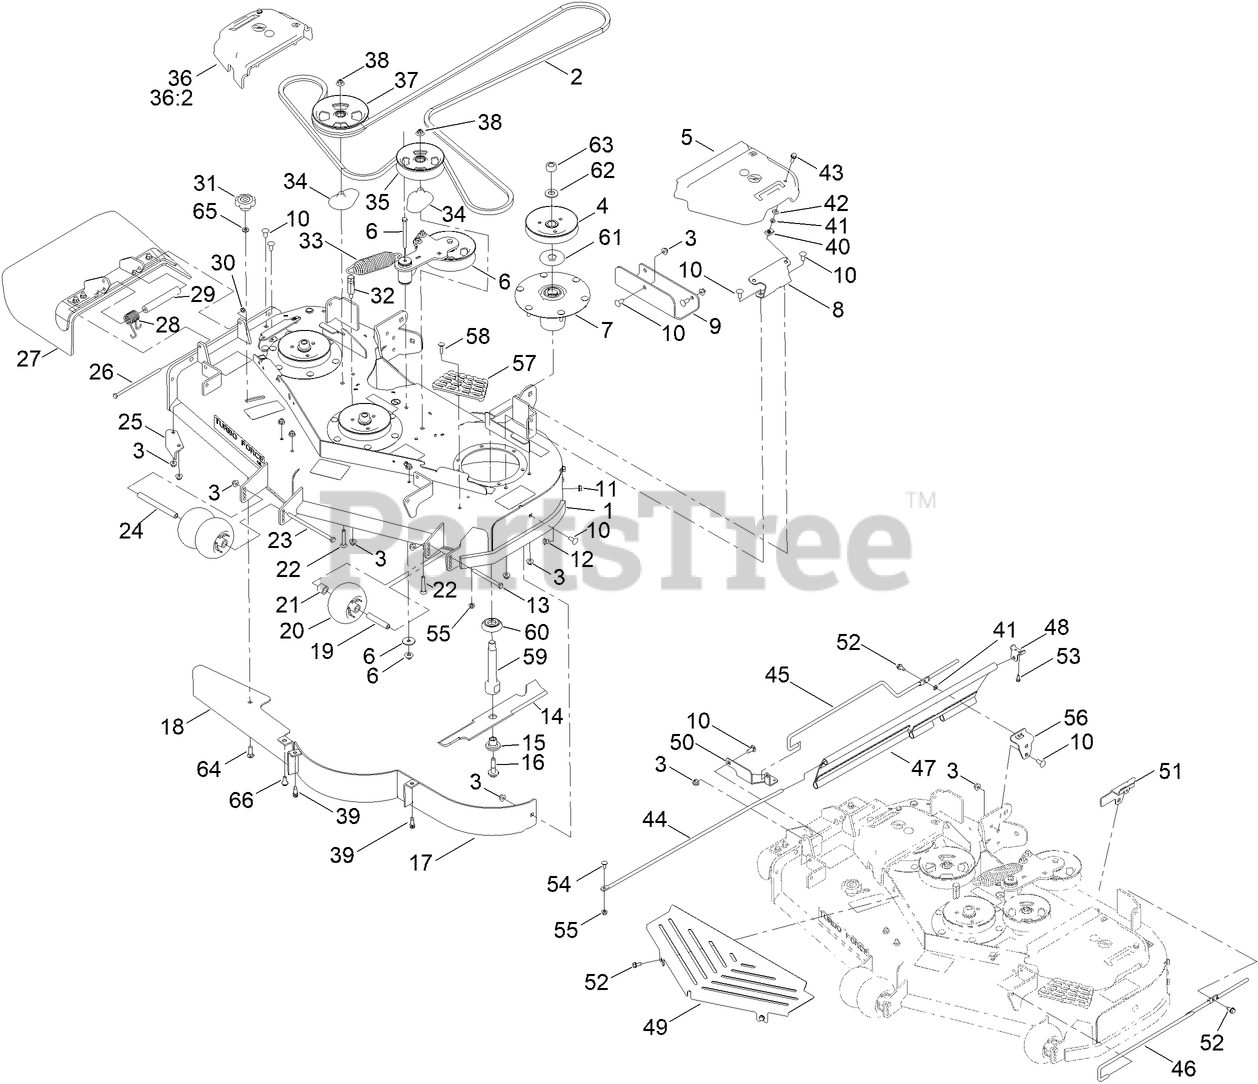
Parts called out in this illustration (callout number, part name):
1	DECK DECAL ASM
2	BELT-V
2	PLUG-PLASTIC
3	NUT-HF, NI
4	SHEAVE,BLADE DRIVE 5.91
5	LH BELT COVER ASM
6	IDLER ARM ASM
7	SPINDLE ASM
8	BRACKET-COVER, BELT
9	PLATE-SKID
10	SCREW-CARR
11	NUT-HHF, WHIZ
12	SCREW-CARR
13	SCREW-HH
14	BLADE-16.50 HIGH FLOW
15	BUSHING-HEX
16	SCREW-SEMS
18	PLATE-BAFFLE, FORMED
19	TUBE-SPANNER
20	ROLLER-SCALP, ANTI
21	TUBE-SPACER
22	BOLT-CARR, SHORT NECK
23	SCREW-HH
24	SPACER-WHEEL
25	BAFFLE-DISCHARGE
26	SCREW-HH
27	RUBBER DEFLECTOR ASM
28	SPRING-TORSION
29	SPACER
30	NUT-LOCK, NI
32	ANCHOR-SPRING, TALL
33	SPRING-EXTENSION
34	SPACER-PULLEY
35	PULLEY-IDLER,FLAT
36	RH BELT COVER ASM
36:2	PLUG-PLASTIC
37	PULLEY-IDLER, FLAT
38	NUT-FLANGE, NI
40	NUT-U
41	NUT-PUSH
42	WASHER-THRUST
43	SCREW-HHF
44	ROD-SUPPORT, UPPER
45	ROD-SUPPORT, LOWER (RH)
46	ROD-SUPPORT, LOWER (LH)
47	GUARD-SIDE
48	BRACKET-MOUNTING, UPPER
49	SHIELD-FRONT
50	BRACKET-MOUNTING, FRONT
51	BRACKET-MOUNTING, REAR (LH)
52	SCREW-HWHTF
53	SCREW-HWH
54	SCREW-CARR
55	NUT-HF, NI
56	BRACKET-MOUNTING, REAR (RH)
57	STEP-DECK
58	SCREW-CARR
59	SHAFT-SPINDLE
60	GUARD-BOTTOM
61	GUARD-BEARING, TOP
62	WASHER
63	NUT-HEX
64	BOLT-CARR
65	WASHER-HARDENED
66	BOLT-SHOULDER
